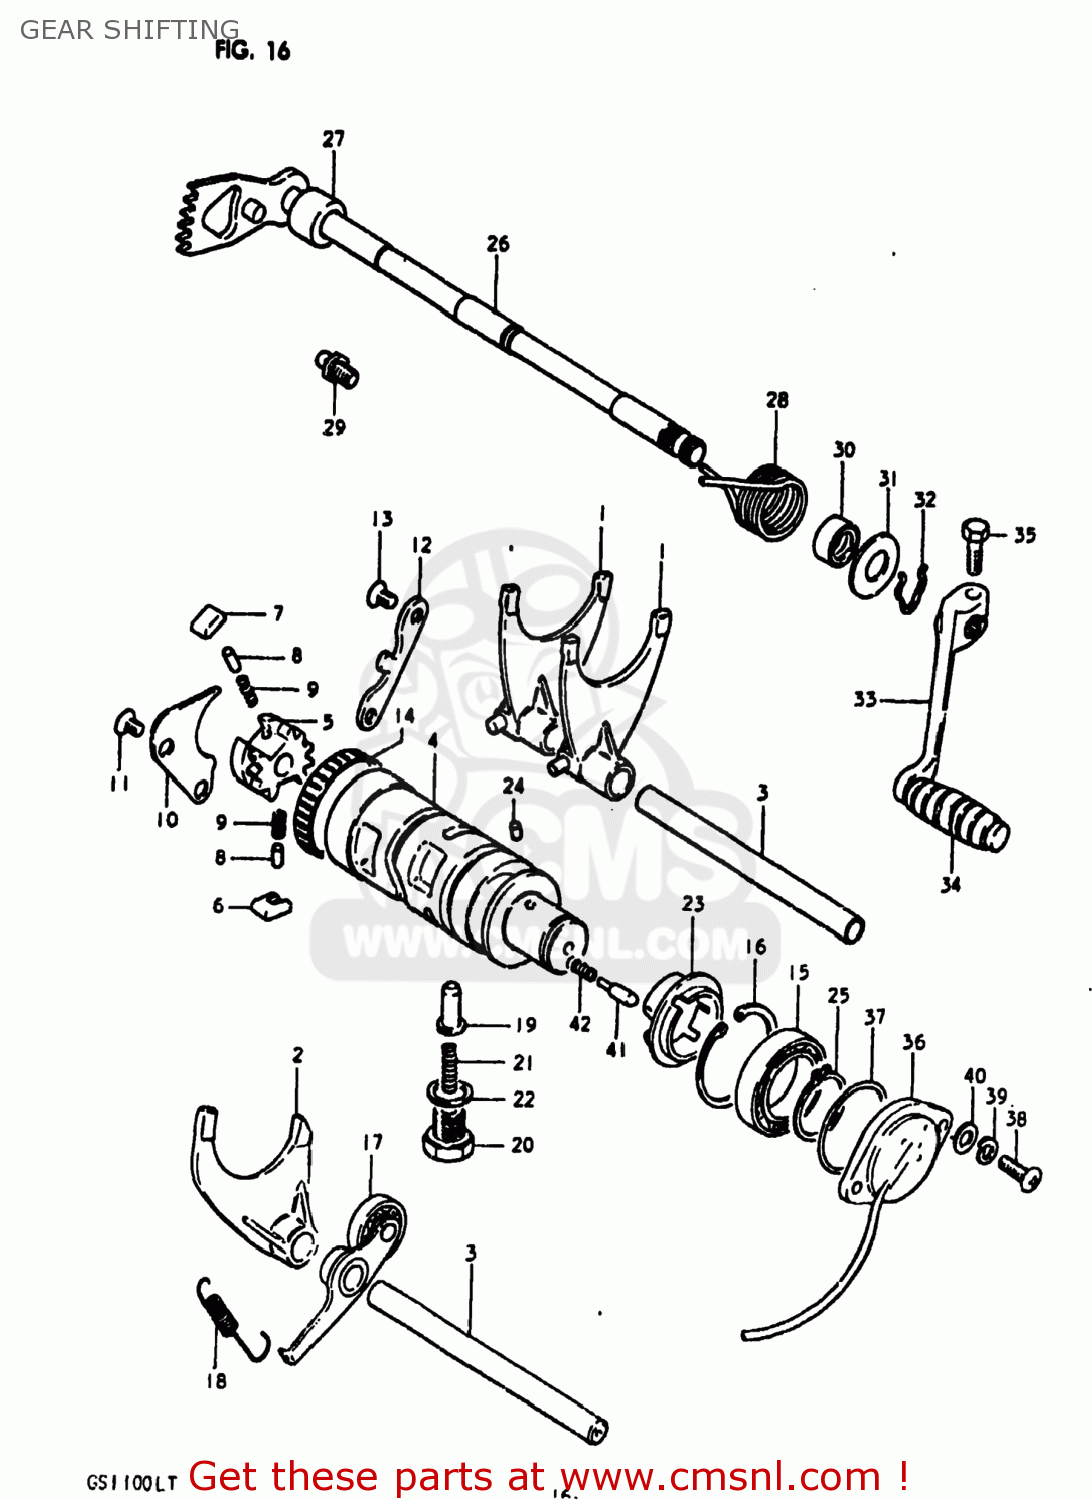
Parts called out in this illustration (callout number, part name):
1	FORK,GEAR SHIFT NO.1
2	FORK,GEAR SHIFT NO.2
3	SHAFT,GEAR SHIFT FORK
4	CAM,GEAR SHIFT
5	RETAINER,GEAR SHIFT CAM
6	PAWL,GEAR SHIFT NO.1
7	PAWL,GEAR SHIFT NO.2
8	PIN(5X8)
9	SPRING
10	LIFTER,GEAR SHIFT PAWL
11	SCREW
12	GUIDE,GEAR SHIFT CAM
13	SCREW
14	BEARING(43X49X12)
15	BALL BEARING
16	CIRCLIP
17	STOPPER,GEAR SHIFTING
18	SPRING
19	STOPPER,GEAR SHIFT CAM NO.2
20	HOLDER,GEAR SHIFT CAM STOP SPR
21	SPRING
22	GASKET(14X19.2X2) (NAS)
23	PLATE,GEAR SHIFT CAM STOPPER
24	PIN 4X6
25	CIRCLIP
26	SHAFT,GEAR SHIFT
27	SPACER(12X20X15.3)
28	SPRING
29	STOPPER,GEAR SHIFT CAM
30	OIL SEAL
31	WASHER (12.5X27X1.6)
32	SPRING,RETAINER
33	LEVER ASSY,GEAR SHIFT
34	RUBBER,GEAR SHIFT PEDAL
35	BOLT
36	BASE ASSEMBLY,NEUTRAL SWITCH TERMINAL
37	O RING(D:2.4,ID:36.5)
38	SCREW
39	LOCK WASHER
40	WASHER
41	PIN(5X15.5)
42	SPRING
